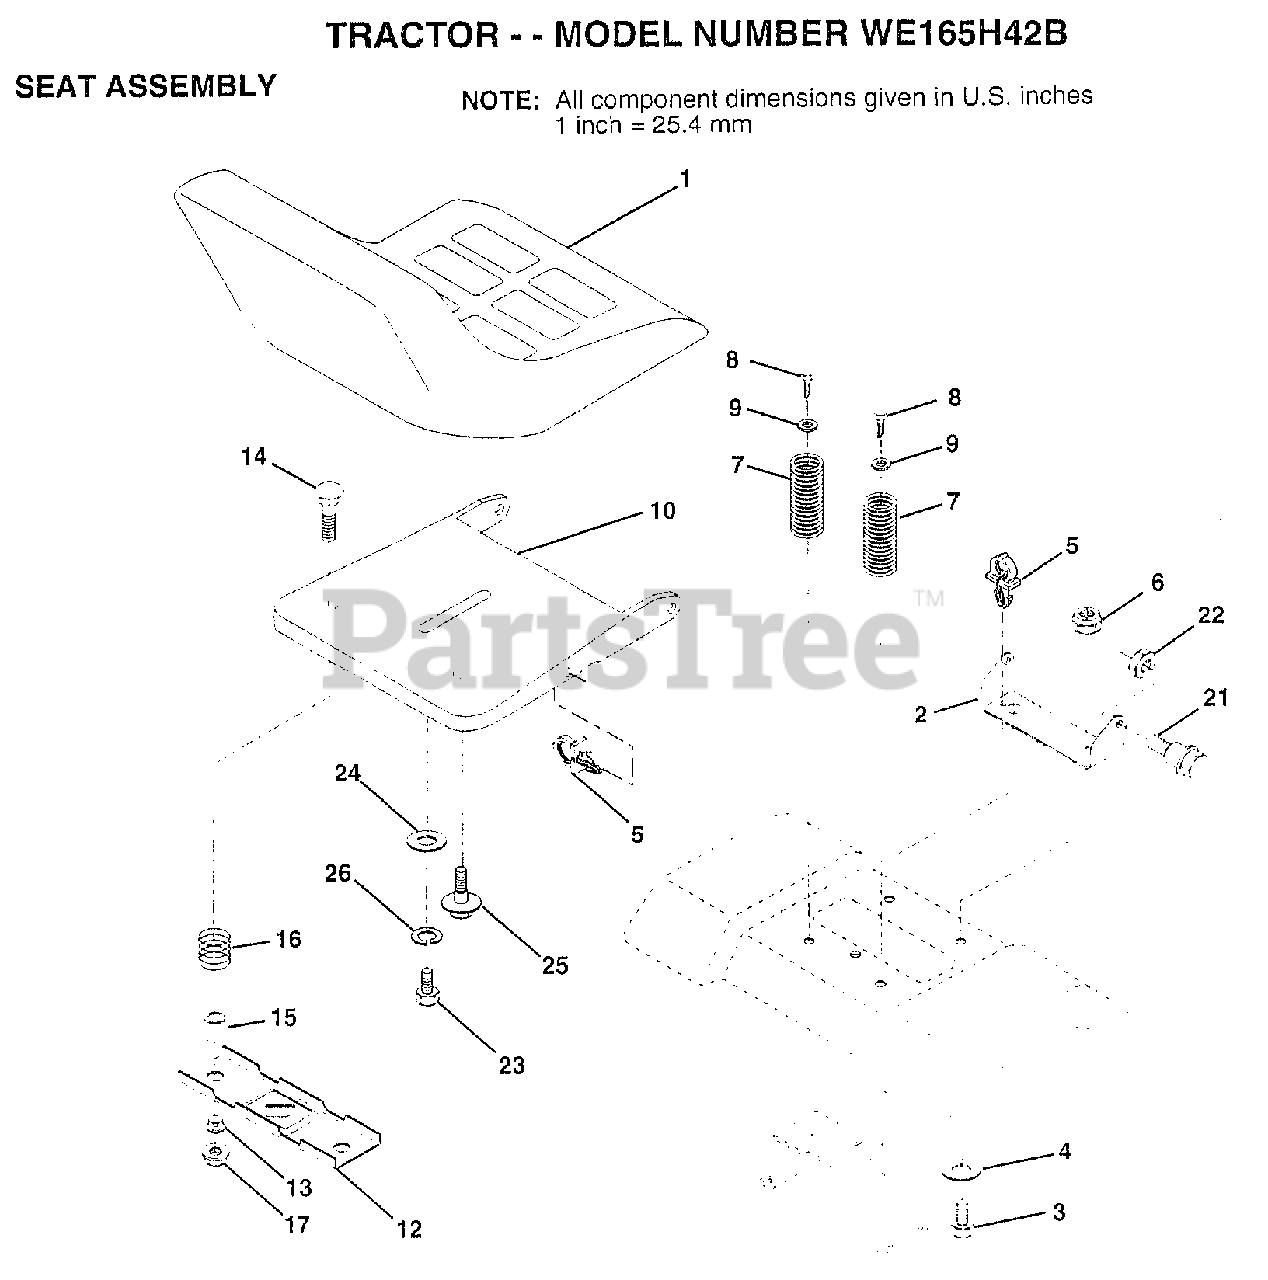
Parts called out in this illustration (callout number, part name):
2	BRACKET PVT SEAT
3	BOLT
4	WASHER PM
5	CLIP.PUSH-IN.HING
6	NUT
7	SPRING COMPRESSIO
8	SCREW GTV
9	WASHER
10	PAN-SEAT
12	BRKT SWITCH
13	BUSHING
14	BOLT-RD HD SQ NK
15	SPLIT SPACER
21	"BOLT,SHOULDER"
22	NUT
23	BOLT
24	WASHER
25	"BOLT,SHOULDER"
26	LOCKWASHER
